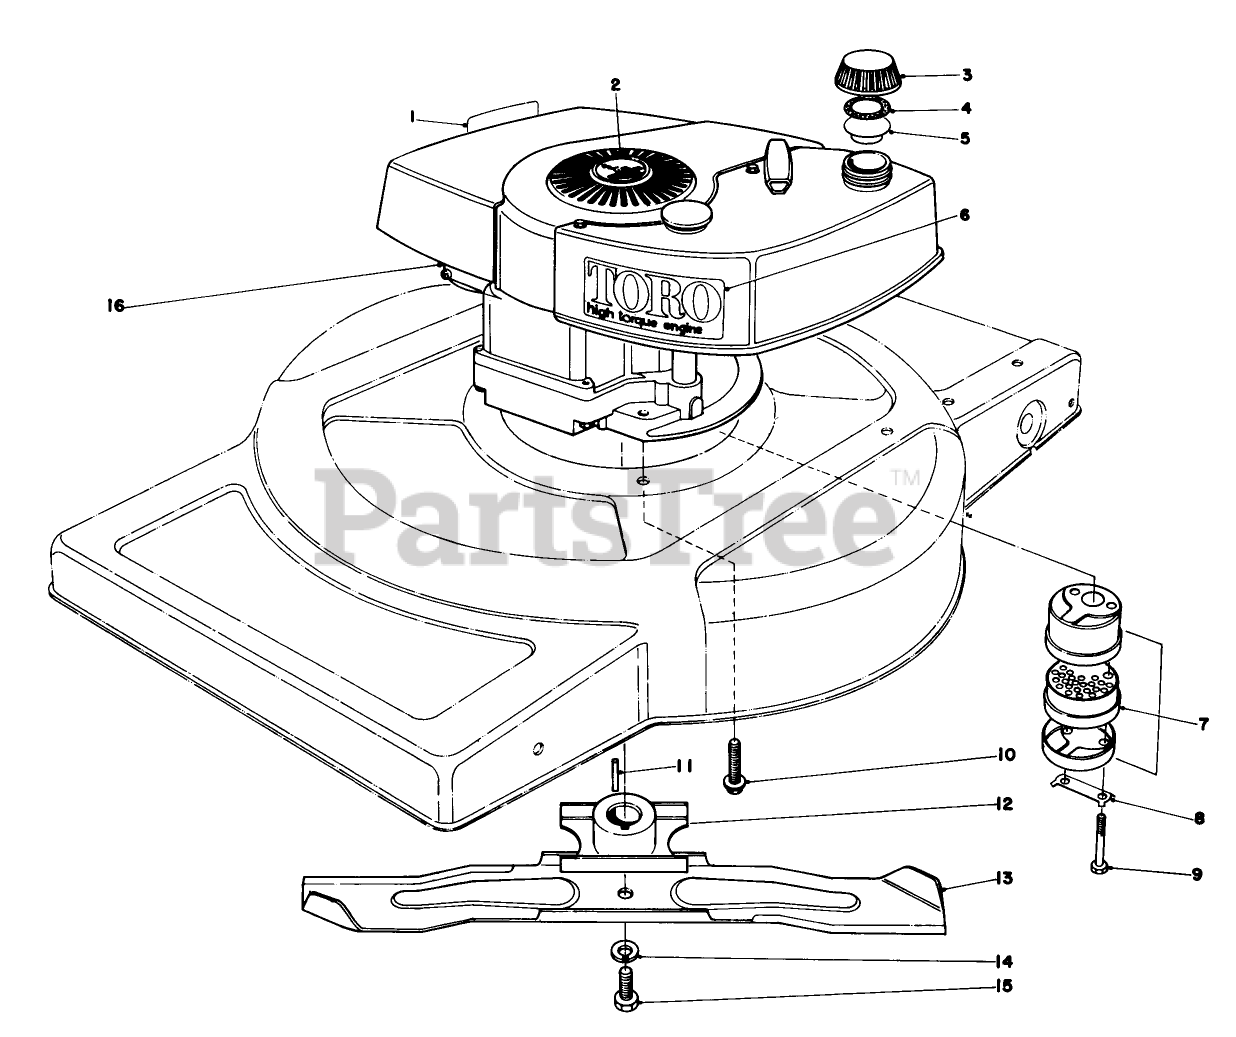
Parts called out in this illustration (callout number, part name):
1	Decal-Maintenan
2	PLUG BUTTON
3	Gas Cap (Incl. Ref. #4 & 5)
4	GASKET
5	GAS CAP BAFFLE
6	High Torque
7	Muffler Assy. (Incl. Ref. #8 & 9)
8	CLIP - LOCKING
9	SCREW-HH
10	SCREW-HWHTF
11	KEY-SQUARE
12	BLADE RETAINER WA(BLACK)
13	Blade
14	WASHER-LOCK
15	BLADE SCREW
16	Engine
